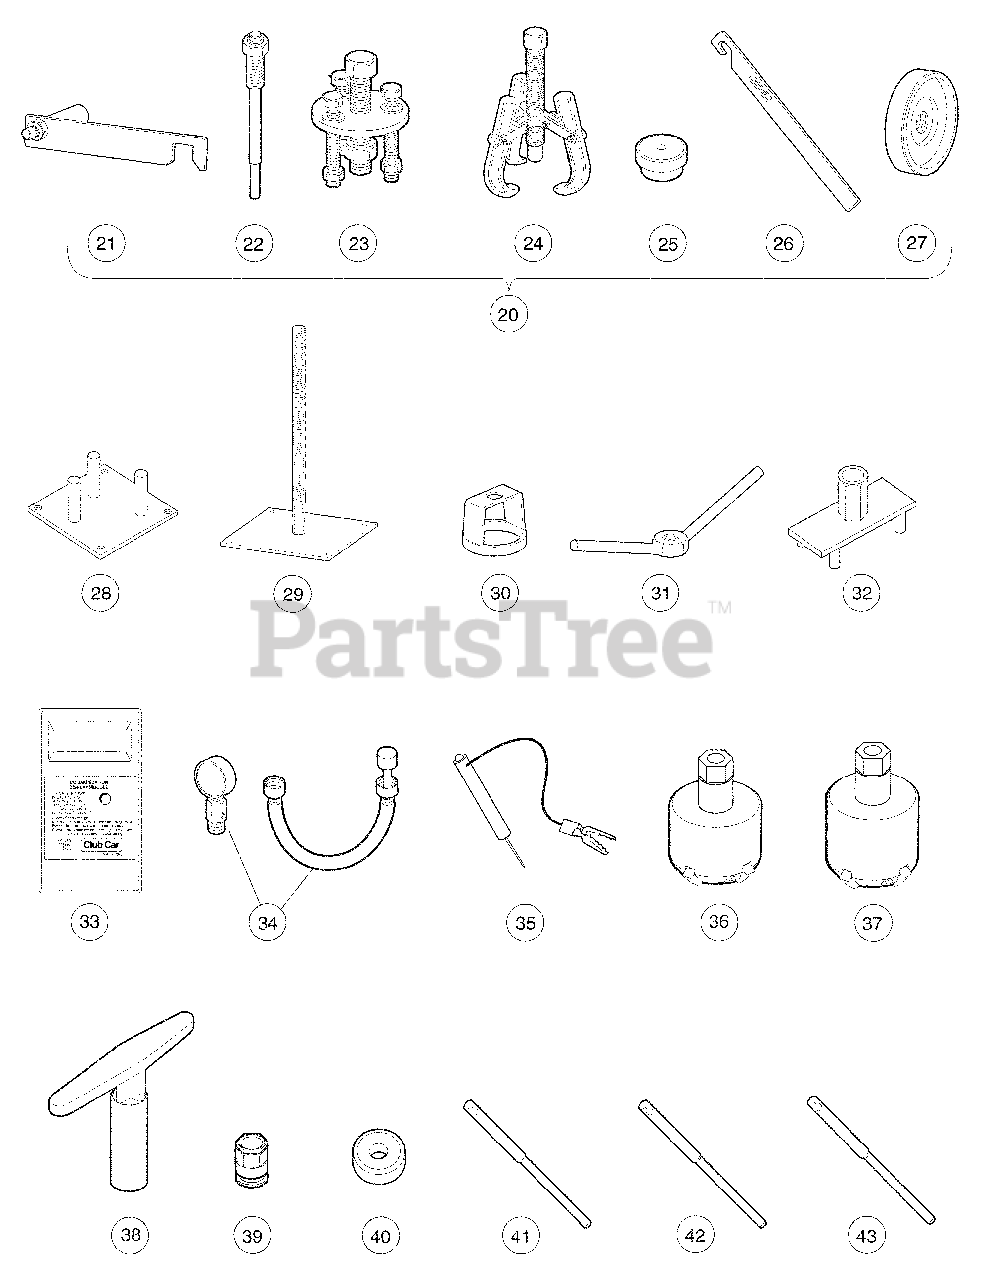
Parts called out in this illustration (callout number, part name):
1	Accelerator Pedal Adjustment Tool
2	Adhesive, Guide Ring, 3-Gram Tube
4	Battery Discharge Machine, 36/48 Volt
5	Battery Terminal Protector Spray
6	Battery Thermometer
7	Bearing and Oil Seal Remover Assembly
8	Bearing Driver Set
9	Bearing Puller
10	Bearing Puller Wedge Attachment
11	Brake Adjustment Tool
12	Brake Cable Release Tool
13	Brake Pedal Adjustment Tool Kit
14	Brake Pedal Adjustment Tool
15	Brake Pedal Tension Tool
16	Calibration Test Module
17	Cam Installation Tool
18	Charger Bezel Tool
19	Clutch Removal Tool (for 4x4 vehicles)
20	Clutch Tool Kit
21	Clutch Alignment Tool
22	Drive Clutch Puller
23	Drive Clutch Hub Puller
24	Driven Clutch Cam Puller
25	Driven Clutch Puller Plug
26	Drive Clutch Holder Tool Assembly
27	Press Weldment
28	Drive ClutchFixed Sheave Tool (for 4x4 vehicles)
29	Driven Clutch Spring Compression Base (for 4x4 vehicles)
30	Driven Clutch Spring Compression Collar (for 4x4 vehicles)
31	Driven Clutch Spring Compression Nut (for 4x4 vehicles)
32	Drive Clutch Spider Removal Tool (for 4x4 vehicles)
33	Communication Display Module
34	Compression Gauge and Adapter
35	Continuity Tester
36	Cutter, Valve Seat, #122
37	Cutter, Valve Seat #115
38	Wrench, T, #505
39	Adapter, T-Wrench
40	Cutter, Valve Seat, 60 Degree (requires item 51)
41	Pilot, 6.6 MM
42	Pilot, 6.62 MM
43	Pilot, 6.65 MM
44	Dry Moly Lubricant
45	Flywheel Puller Kit
46	Gauge, Carburetor Float Level
48	Governor Shaft Installation Tool
49	Hydraulic Brake Adjuster (for HUV 4213)
50	Hydrometer
51	Internal Retaining Ring Pliers
52	IQ Display Module (IQDM) Kit
53	IQ Display Module (IQDM-P) Kit
54	Adaptor, Cable
55	IQDM Series 2 Cable
56	IQDM Series 1 Cable
57	Liquid Gasket
58	Moly-Teflon Lubricant (4-oz. (113-gram) tube)
59	Paint, Touch-Up – Beige
59	Paint, Touch-Up – Black
59	Paint, Touch-Up – Burgundy
59	Paint, Touch-Up – Classic Blue
59	Paint, Touch-Up – Dark Gray
59	Paint, Touch-Up – Dark Green
59	Paint, Touch-Up – Gray
59	Paint, Touch-Up – Red
59	Paint, Touch-Up – Royal Blue
59	Paint, Touch-Up – White
60	Paint, Precedent Underbody – Gray
61	Paint Pen, Touch-Up, Precedent Underbody – Black
62	Piston Ring Compressor Kit (FE290, FE350 and FE400 engines)
63	Piston Ring Pliers
64	Puller, Special Use (for Kubota D722 Diesel Engines)
65	Retaining Ring Pliers, 45° External
66	Retaining Ring Pliers, 90° Internal
67	Safety First Card (50 per pack)
68	Seal Puller
69	Spanner Wrench
70	Steering Column Bearing Press Tool
71	Steering Column Retaining Ring Tool
72	Steering Wheel Puller Tool
73	Tachometer
74	Tachometer Diesel Probe (for use with item 73)
75	Transaxle Axle Seal Tool
76	Transaxle Pinion Seal Tool
77	Transmission Tool Kit
82	Valve Clearance Adjuster Screw Holder (for FE290 engines only)
83	Valve Guide Driver
84	Valve Guide Reamer (FE290, FE350, and FE400 only)
85	Valve Guide Reamer, 6.6 mm
86	Valve Seat Cutter Guide
87	Valve Seat Cutter T-Wrench
88	Valve Seat Cutter, 45° (32 mm diameter) (for FE290 engines only)
89	Valve Seat Cutter, 45°/30° (35 mm diameter)
90	Valve Spring Compressor
91	Volt Ohm Meter
92	Tool, Tensioning, Starter Generator
